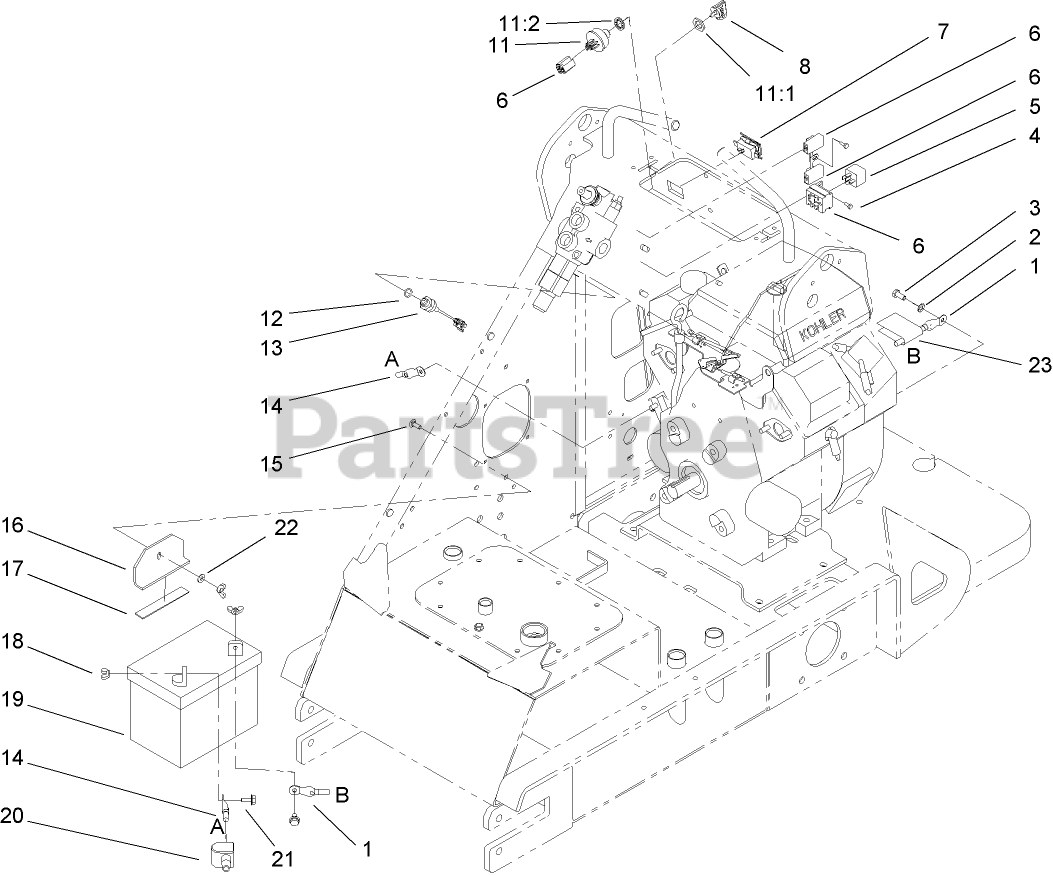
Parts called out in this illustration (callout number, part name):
1	CABLE-BLACK
2	WASHER-LOCK
3	SCREW-HH
4	SCREW-HWHTF
5	RELAY
6	HARNESS-ELECTRICAL
7	METER-HOUR
8	KEY-IGNITION
11	KEY SWITCH ASM
11:2	WASHER-LOCK
12	O-RING
13	SWITCH-BALL
14	WIRE-21 INCH
15	SCREW-CARR
16	CLAMP-BATTERY
17	PAD-FOOTREST
18	NUT-WING
19	BATTERY-DRY
20	BOOT-TERMINAL, RED
21	SCREW-HHF
22	WASHER-FLAT
23	DECAL-INSTRUCTIONS, CHARGING
